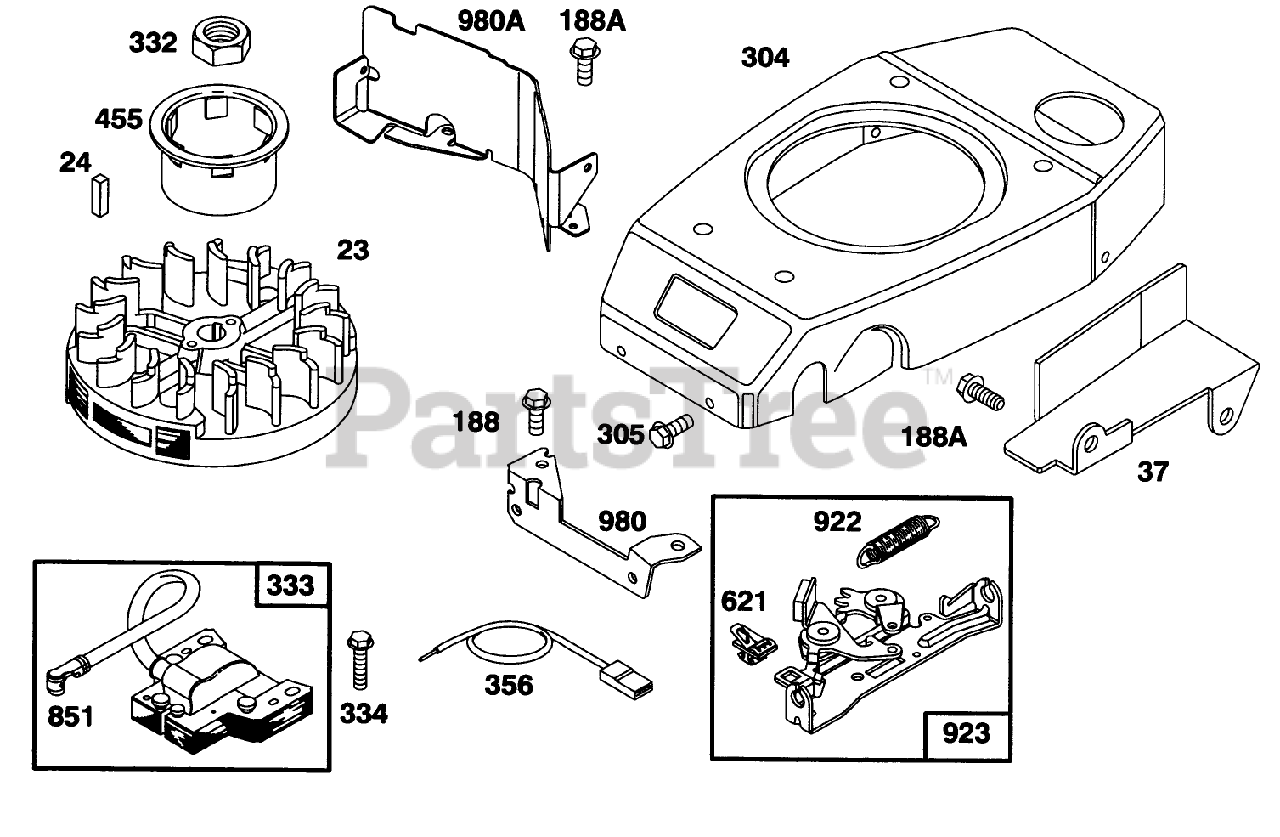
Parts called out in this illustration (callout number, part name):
24	KEY - FLYWHEEL
188A	SCREW - SEM
304	HOUSING - BLOWER
305	SCREW - HEX HEAD
332	NUT - HEXAGON
356	WIRE - GROUND
621	STOP SWITCH
980	BRACKET-BLOWER HSG
980A	BLOWER HSG BRACKET
